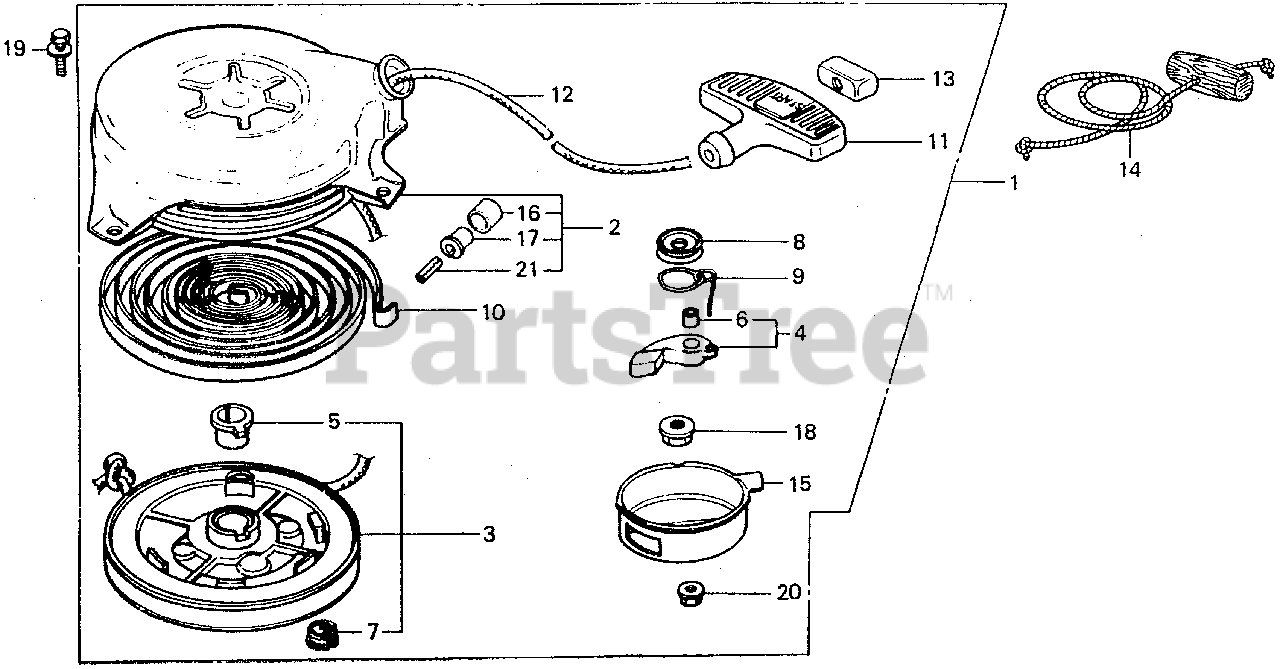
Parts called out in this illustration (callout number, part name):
1	STARTER ASSY., RECOIL *R8* (Honda Code 0957050). (BRIGHT RED)
2	CASE, STARTER *R8* (Honda Code 1024405). (BRIGHT RED)
3	REEL, STARTER
4	RATCHET
5	BOSS, REEL
6	BUSH, RATCHET
7	BUSH, REEL STARTER
8	PLATE, FRICTION
9	SPRING, FRICTION
10	SPRING, RETURN
11	GRIP, STARTER
12	ROPE, STARTER (#5X55")
13	SUPPORT, GRIP
14	ROPE, STARTER (#5X55") Use from Engine SN 1453515.
15	COVER, STARTER REEL Use up to Engine SN 1533900.
16	ROLLER, GUIDE
17	BUSH, ROLLER
18	NUT, SELF-LOCK (8MM)
19	BOLT-WASHER (6X10)
20	NUT, FLANGE (5MM)
21	PIN, SPRING (3X18)
